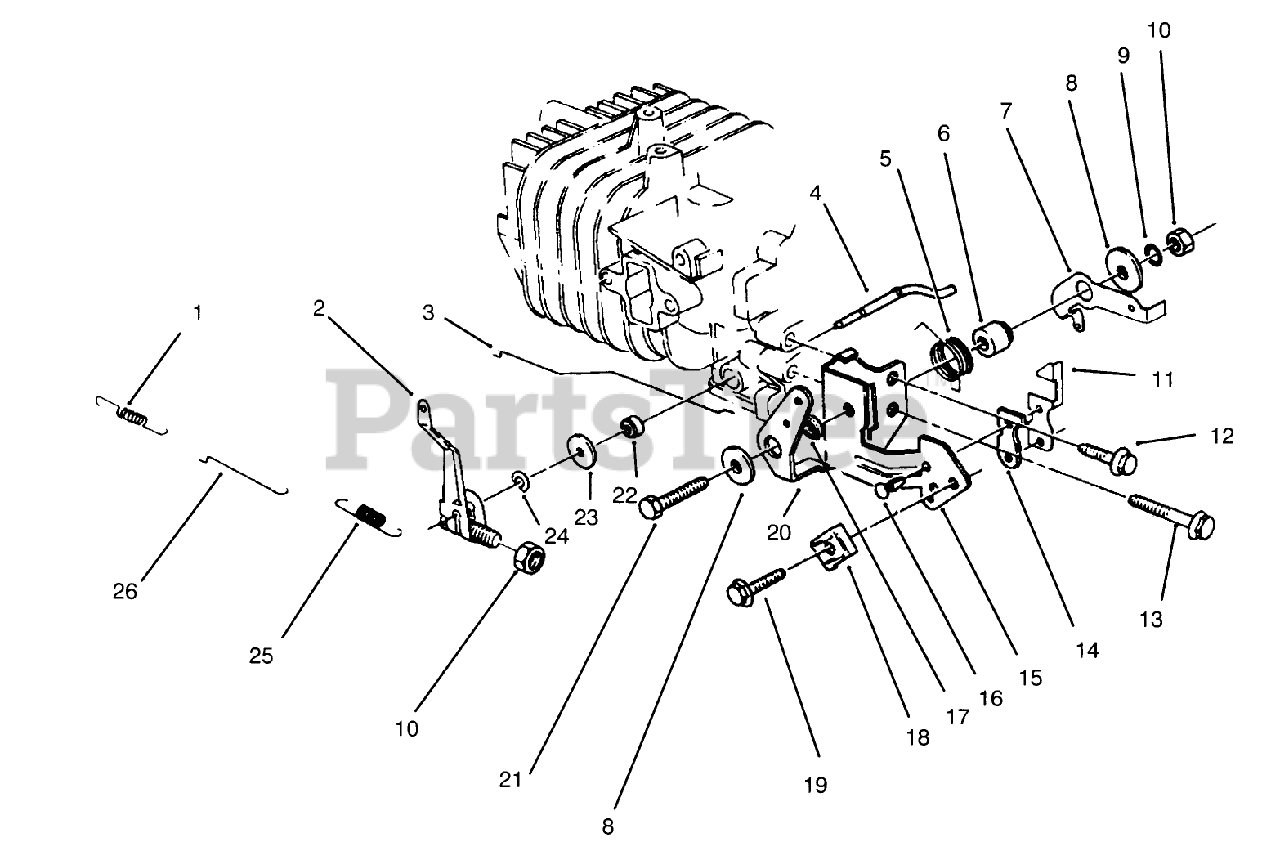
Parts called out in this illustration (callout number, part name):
1	SPRING
4	SHAFT
5	SPRING-CHOKE LEVER
6	SPACER
7	LEVER-SPRING, GOVERNOR
8	WASHER
9	LOCKWASHER
11	TERMINAL-KILL SWITCH
14	INSULATOR-KILL SWITCH
15	BRACKET
16	RIVET
17	SPACER-CHOKE LEVER
18	CLAMP
22	SEAL-OIL
23	WASHER
25	SPRING-GOVERNOR
26	ROD-CARBURETOR
